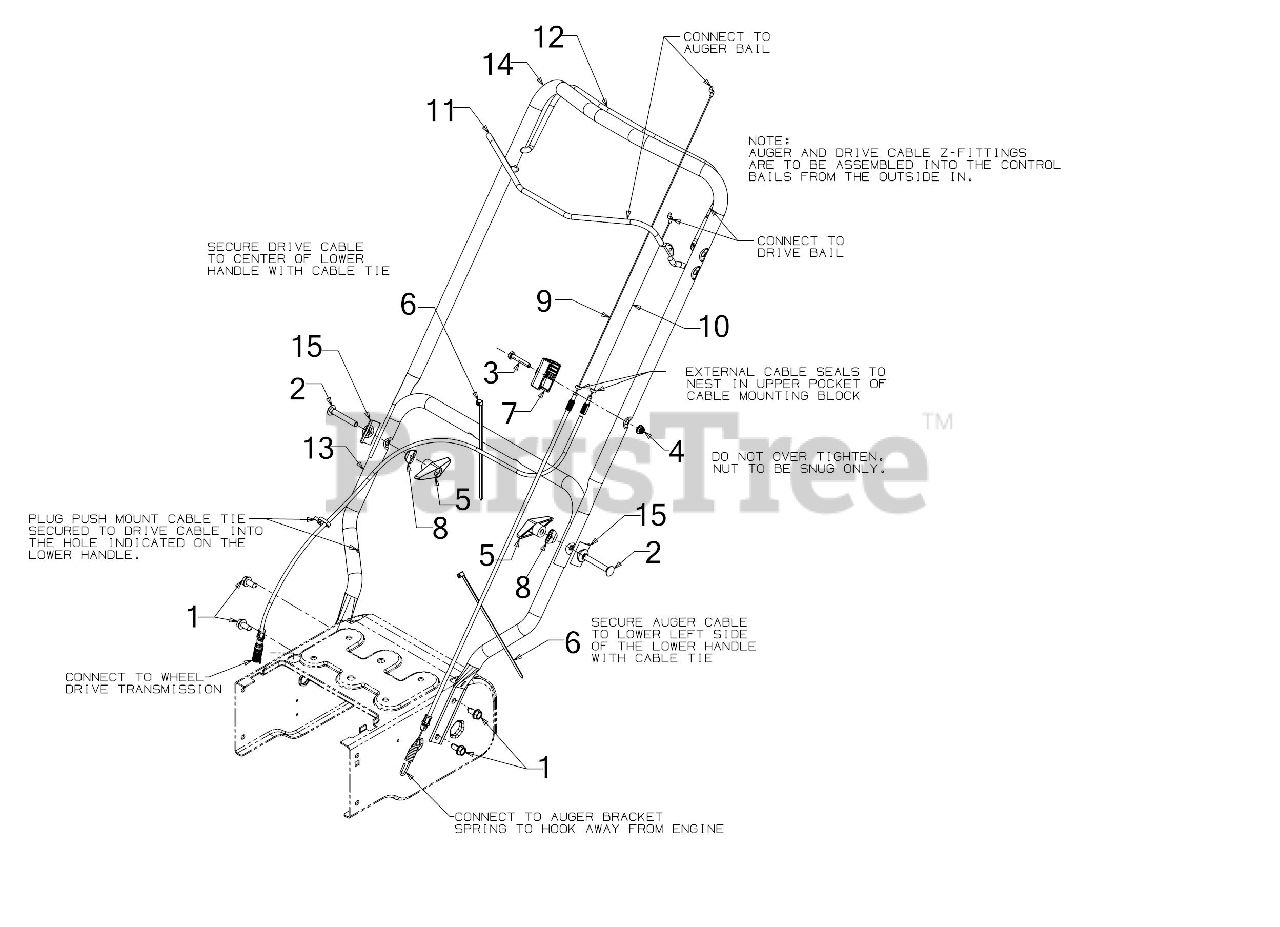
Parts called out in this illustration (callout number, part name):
1	SCREW 5/16-18 x .750
2	SCRE W5/16-18 x 2.25 GR5
3	SCREW 1/4-20 x 1.50 GR.5
4	FLANGE LOCK NUT
5	WING NUT KNOB
6	7" CABLE TIE
7	CABLE MOUNT
8	SADDLE WASHER
9	AUGER CLUTCH CABLE
10	TRANSMISSION CLUTCH CABLE
11	AUGER CONTROL BAIL
12	DRIVE BAIL
13	LOWER HANDLE
14	UPPER HANDLE
15	HANDLE TAB
